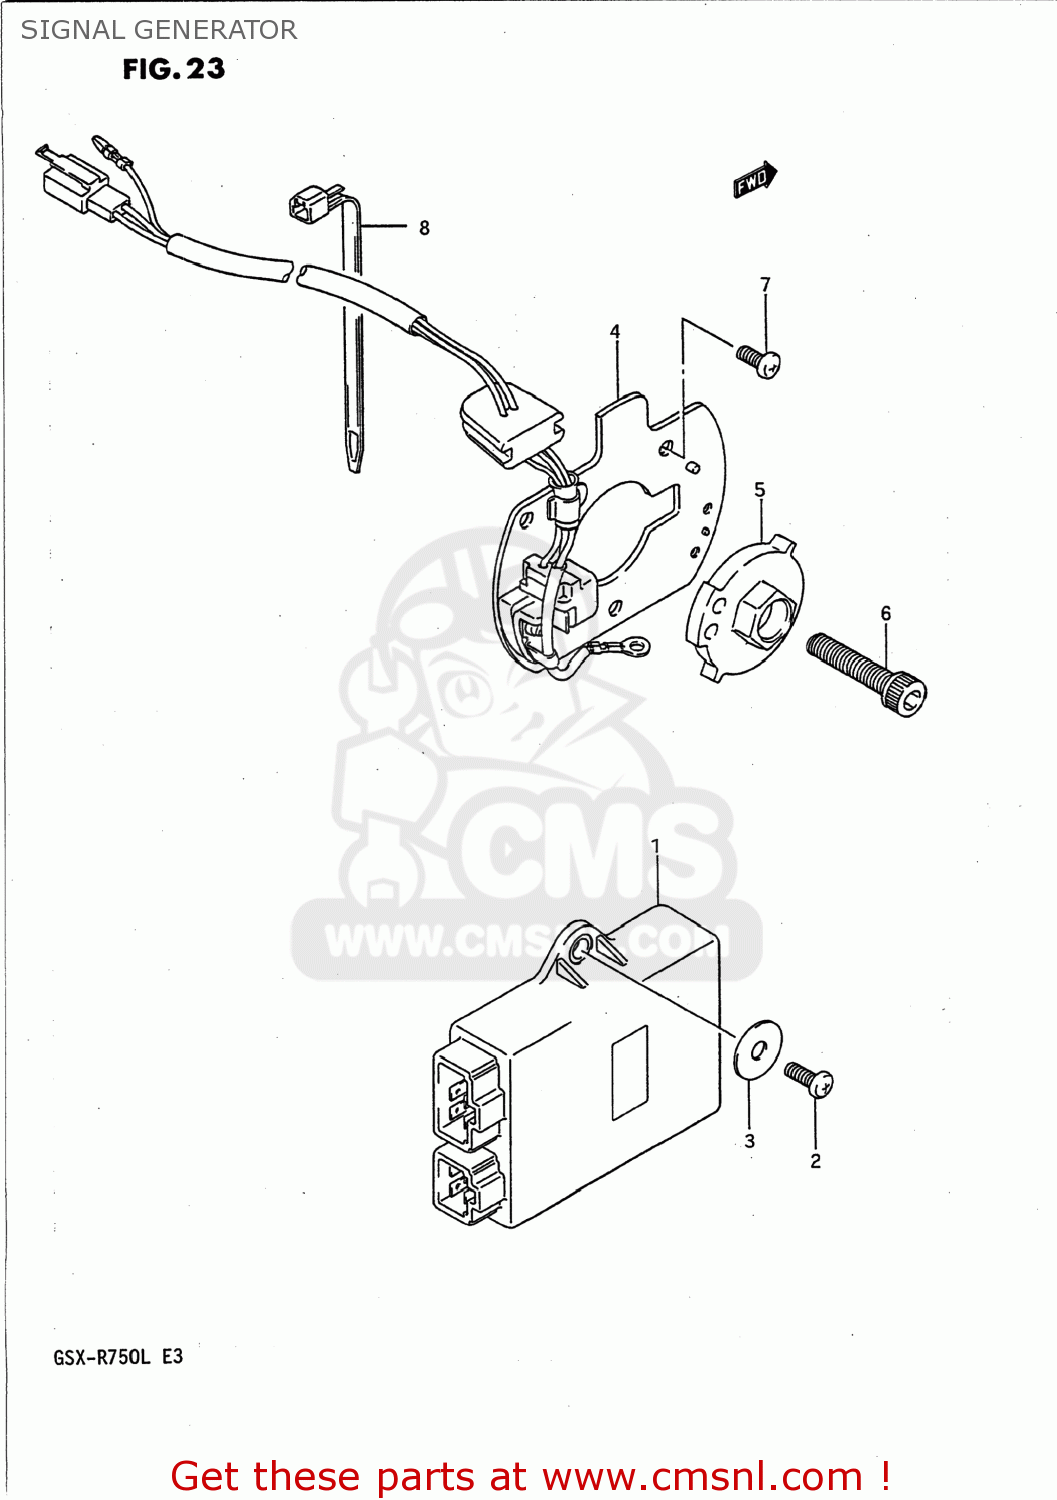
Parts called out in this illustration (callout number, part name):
1	IGNITER UNIT
2	SCREW
3	WASHER, LOWER
4	GENERATOR ASSY,SIGNAL
5	ROTOR,SIGNAL
6	BOLT
7	SCREW
8	CLAMP(L:125)
